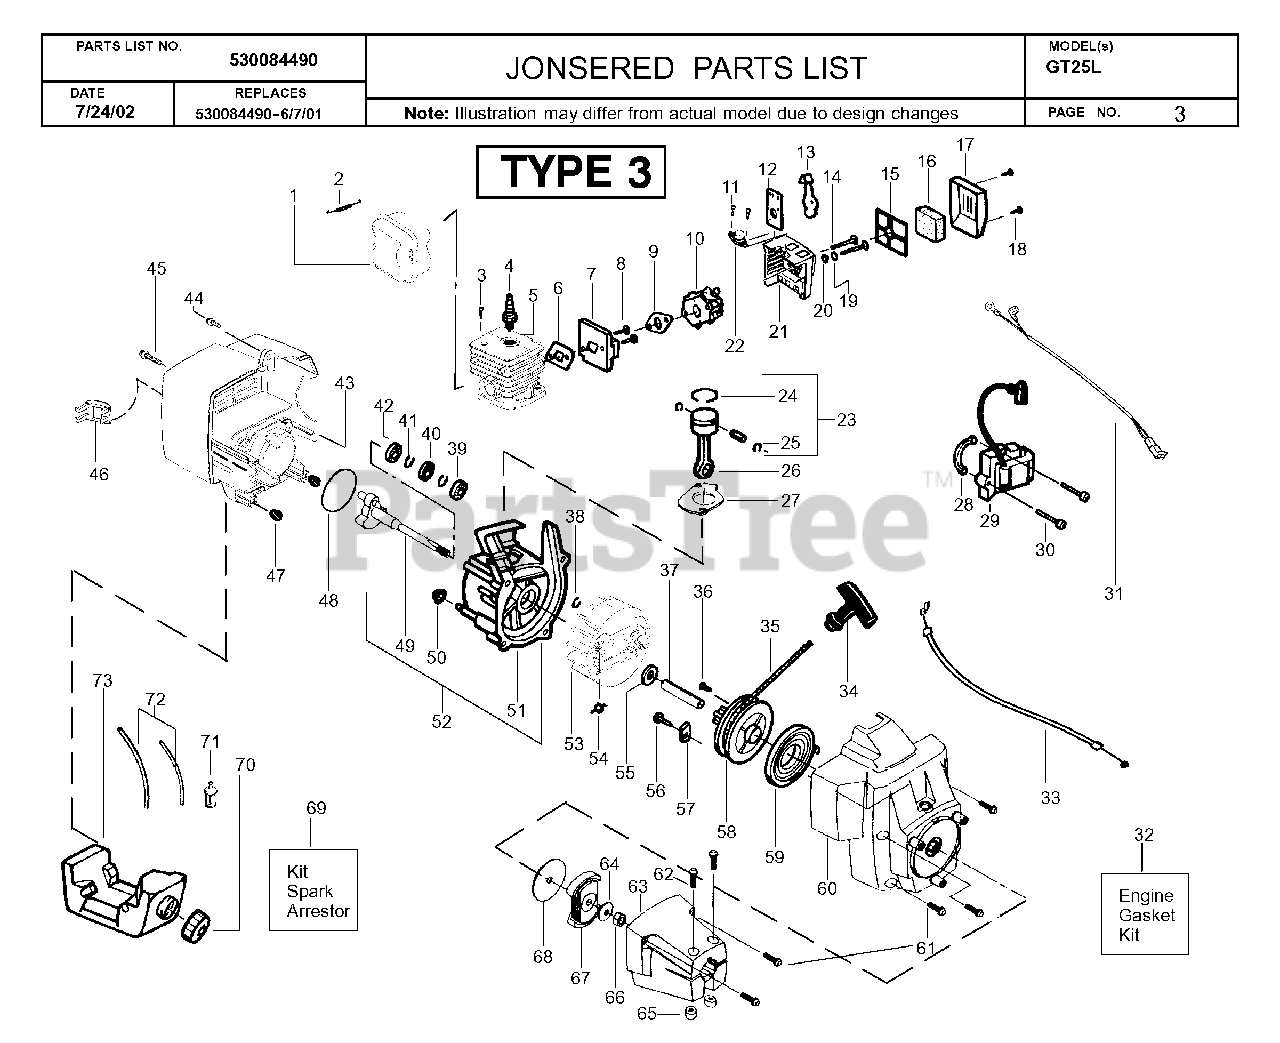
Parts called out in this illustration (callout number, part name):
1	KIT-MUFFLER
4	PLUG-SPARK (RCJ-6Y)
6	GASKET KIT
8	SCREW - CARB. ADAPTOR
9	GASKET KIT
10	CARBURETOR W/CAPS
11	SCREW - PRIMER ASSEMBLY
12	CHOKE PLATE
13	CHOKE SHUTTER
14	SCREW
15	FILTER PLATE
16	AIR FILTER FOAM
17	AIR FILTER COVER
19	CHOKE SPACER
22	AIR PURGE BUBBLE
23	PISTON
24	PISTON RING
25	WRIST PIN RET.
27	GASKET KIT
28	SPACER - IGNITION MODULE
29	IGNITION MODULE
31	LEAD WIRE ASSEMBLY
32	GASKET KIT
34	HANDLE-STARTER
38	RETAINING RING
40	SEALING RING
42	BEARING
45	SCREW - SHROUD
47	SHROUD ISOLATOR
48	GASKET KIT
49	CRANKSHAFT ASSEMBLY
53	FLYWHEEL
54	SPRING STR DOG
56	SCREW 8-16 X 9/16 (PLAS
58	STARTER PULLEY KIT
59	STARTER SPRING
61	SCREW - SHROUD
62	SCREW-10-24 X 1-3/8 (UN
63	CLUTH COVER
64	WASHER FLAT
65	LOCKNUT-HEX 10-24
67	CLUTCH ASSEMBLY KIT
68	FRICTION DISC,CLUTCH 36/41
70	CAP ASSY W/ RETAINER
71	FUEL PICK-UP ASSY
72	KIT-LINE(FUEL)
73	TANK UNIT
